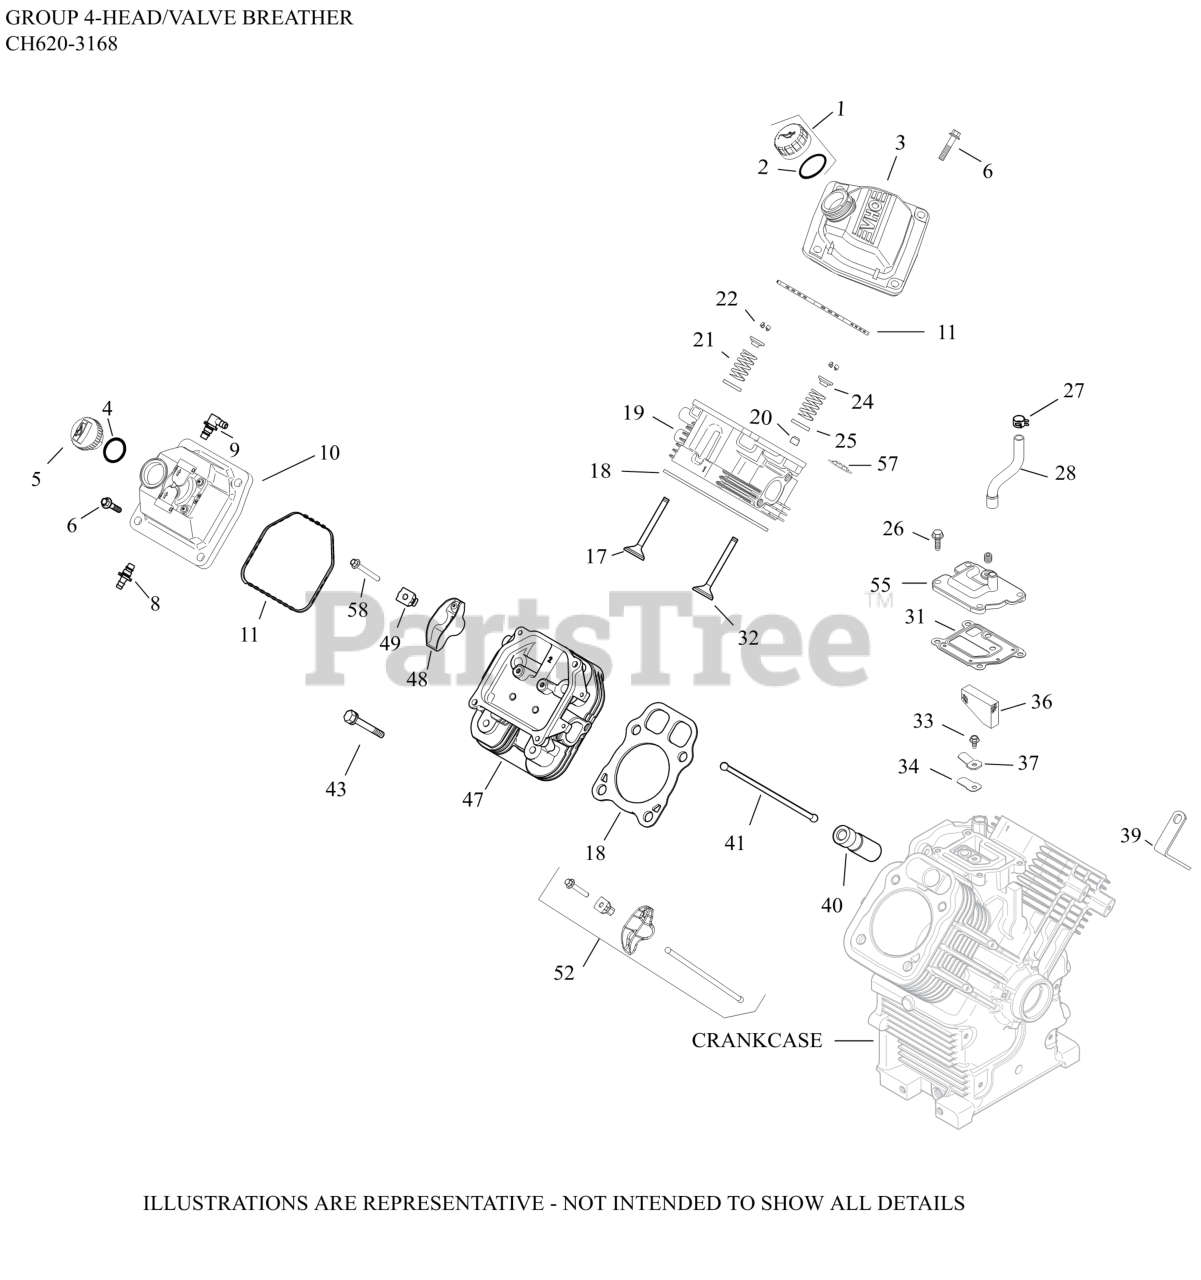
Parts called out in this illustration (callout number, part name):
1	KIT, OIL FILL CAP (YELLOW)
2	O-RING, DIPSTICK
3	KIT, VALVE COVER-OIL FILL
5	CAP ASSY, OIL FILL (YELLOW)
6	SCREW, FLG M6X1.0X30
8	KIT, STRAIGHT FITTING
9	KIT, 90 DEG. FITTING
10	KIT,VALVE COVER-FUEL PUMP
11	O-RING (YELLOW), VALVE CO
17	VALVE, EXHAUST
17	VALVE, EXHAUST (.25)
18	KIT, GSKT CYL HD (C22-23 674CC)
19	KIT, CYLINDER HEAD (#1)-(#2481803S)
20	SEAL, VALVE BAND
21	SPRING, VALVE
22	KIT, RETAINER
24	CAP, VALVE SPRING
25	RETAINER, SPRING
26	SCREW, THREAD FORMING
27	SPRING CLAMP, HOSE
28	KIT, BREATHER HOSE AND CLAMP
31	GASKET, BREATHER
32	VALVE, INTAKE (STD)
32	VALVE, INTAKE (.25)
33	SCREW, FLG THD FRM M5X.8X10
34	REED, BREATHER
36	FILTER, BREATHER
37	RETAINER, REED
39	STRAP, LIFT
40	LIFTER, VALVE HYDRAULIC-USE 25 351 11-S
41	ROD, PUSH
43	SCREW, FLG M10X1.5X90
47	KIT, CYLINDER HEAD (#2)-(#2481804S)
48	ARM, ROCKER
49	PIVOT, ROCKER ARM
52	KIT, VALVE TRAIN
55	COVER, BREATHER
57	RETAINER, VALVE GUIDE (KM)
58	SCREW,HEX FLANGE - USE 25 086 777-S
